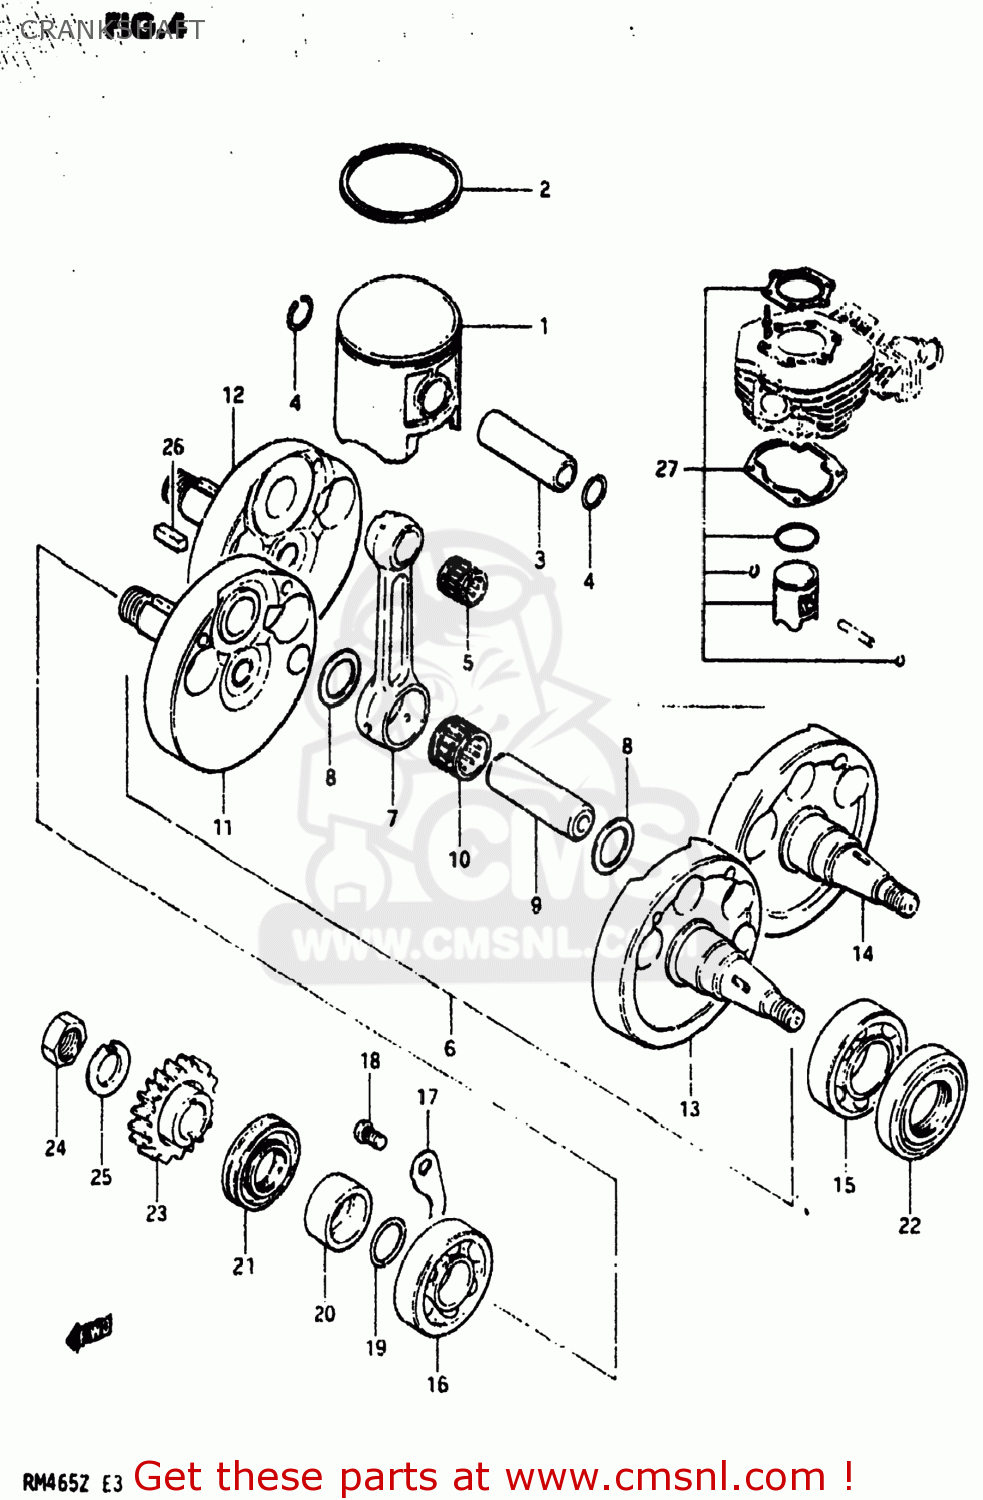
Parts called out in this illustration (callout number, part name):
1	PISTON (86.00MM)
2	RING,PISTON
3	PIN,PISTON (18MM)
4	CIRCLIP
5	BEARING(18X23X22)
6	CRANKSHAFT ASSEMBLY
7	ROD,CONNECTING
8	WASHER (25X30X1.5)
9	PIN,CRANK
10	ROLLER BEARING (25X31X2
11	CRANKSHAFT,RIGHT
12	CRANKSHAFT,RIGHT
13	CRANKSHAFT,LEFT
14	CRANKSHAFT,LEFT
15	BEARING,LEFT
16	BEARING
17	PLATE,CRANKSHAFT OIL S
18	SCREW
19	O-RING (D:3 ID:23.5)
20	SPACER,PRIMARY DRIVE GEAR
21	SEAL,OIL(37X62X9)
22	SEAL,OIL(19.6X37X8)
23	GEAR,PRIMARY DRIVE
24	NUT
25	WASHER
26	KEY
27	PISTON SET
